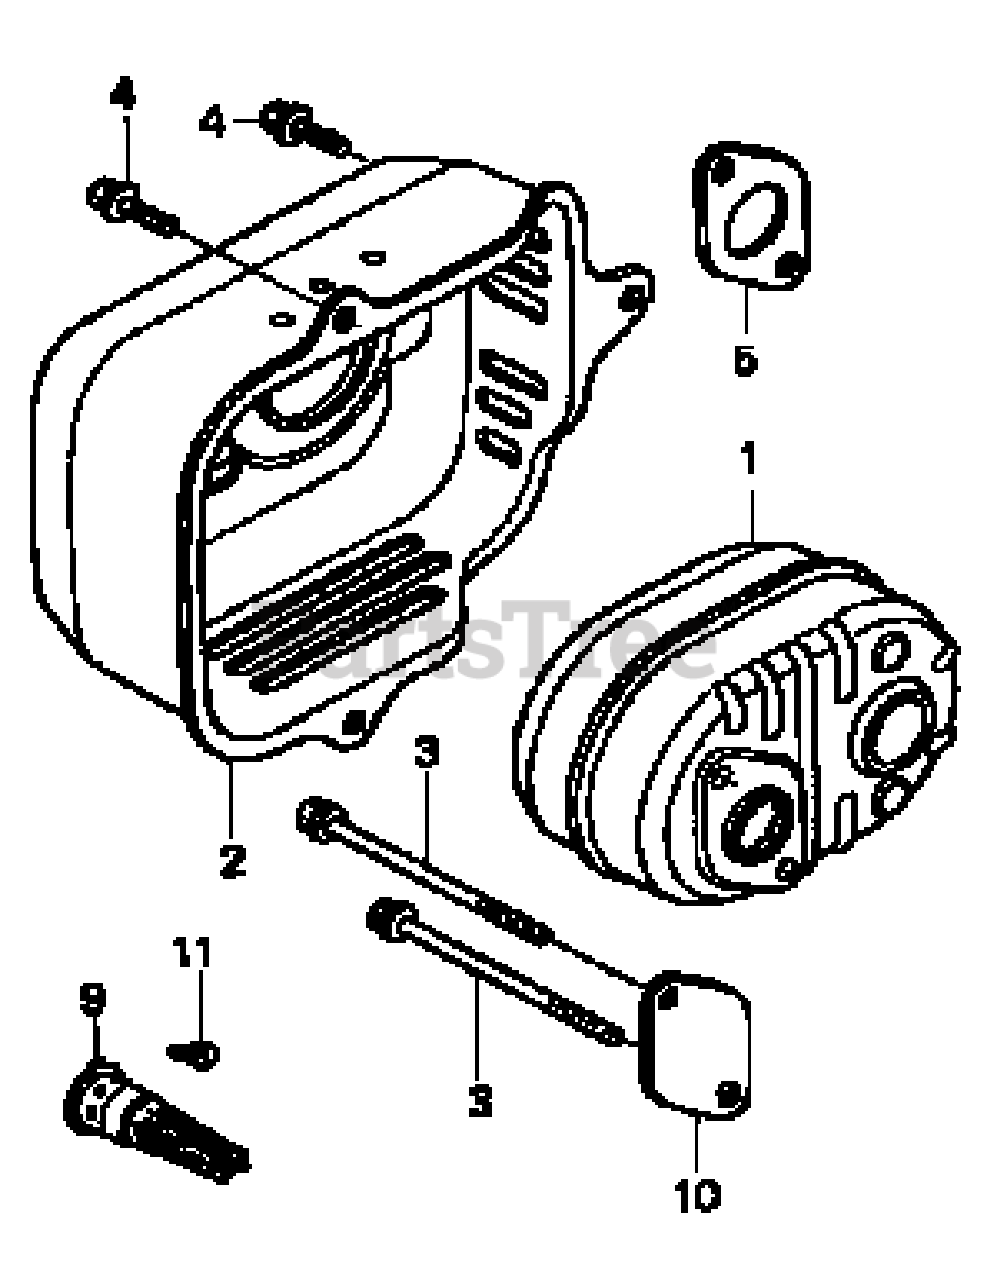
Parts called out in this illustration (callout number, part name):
1	Muffler
2	Muffler Protector
3	Flange Bolt (6x79)
4	Flange Bolt
5	Muffler Gasket
9	Spark Arrester
10	Arrester Number Plate
11	Tapping Screw (4x6)
